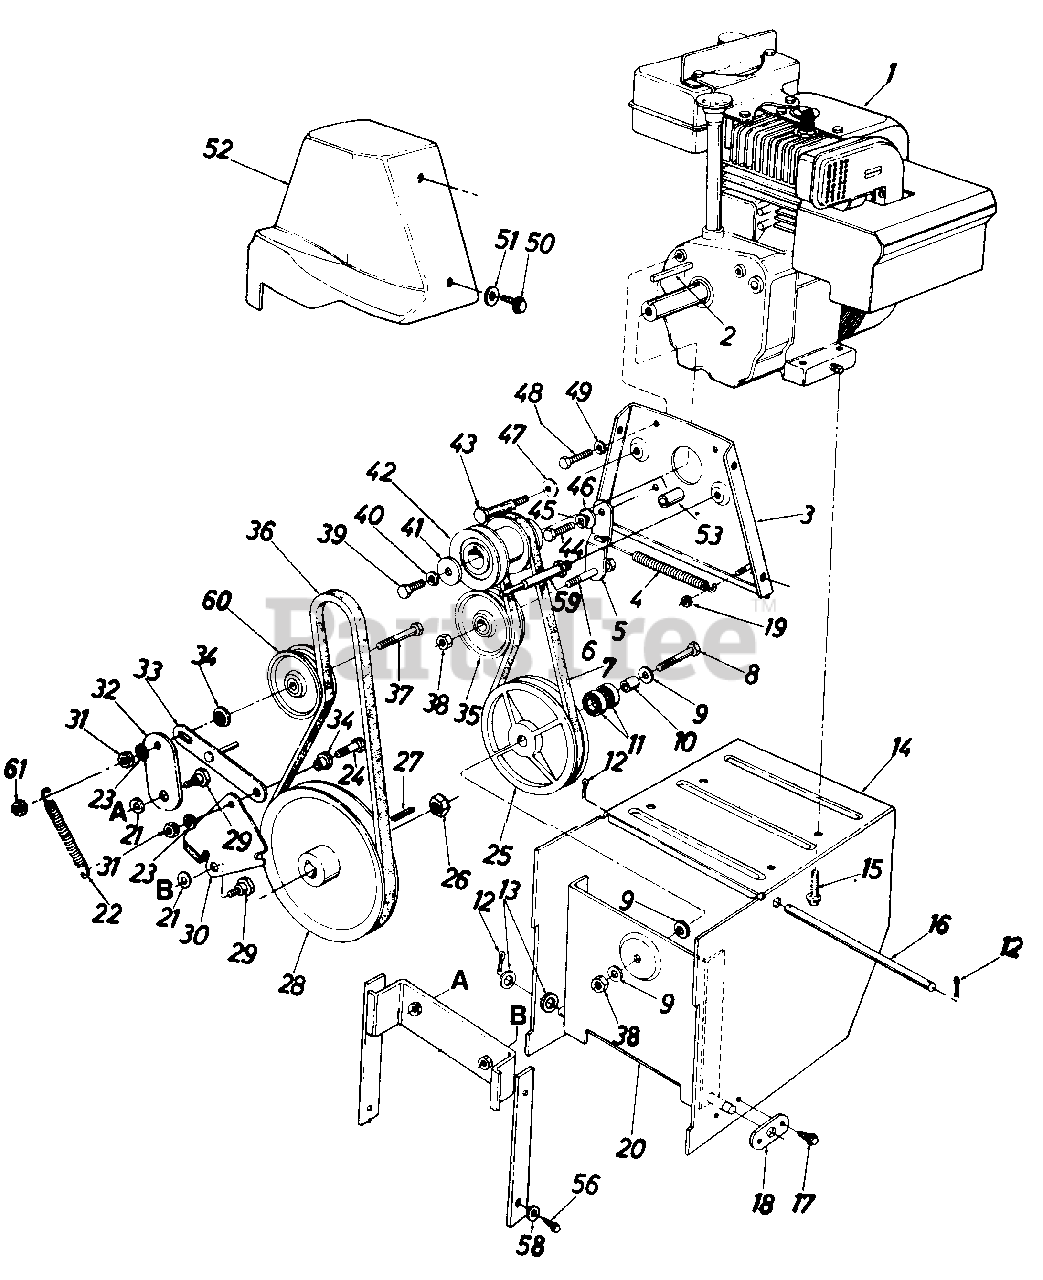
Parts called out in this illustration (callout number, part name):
1	Engine
2	Sq. Key 3/16" x 1.5" Lg.
3	Engine Plate Ass'y.
4	Extension Spring .50" O.D. x 3.97" Lg.
5	Drive Clutch Idler Brkt.
6	Hex Bolt 3/8-24 x 1.25" Lg.
7	"V Belt
8	Hex Bolt 3/8-24 x 1.50" Lg.
9	Bell-Wash. .40" I.D. x .88" O.D. x .06
10	Spacer .38" I.D. x .62" O.D. x.75" Lg.
11	Ball Brg. .62" I.D. x 1.38" O.D. x .44
12	Cotter Pin 3/32" Dia. x .75"
13	Fl-Wash. .53" I.D. x 1.00" O.D. x .125
14	Frame Ass'y.
15	Hex Wash. Hd. Self-Tap Scr. 3/8-16 x 1.25" Lg.
16	Shaft .50" Dia. x 9.50" Lg.
17	Hex Wash. Hd. Self-Tap Scr. 1/4-20 x .50" Lg.
18	Axle Bracket
19	Hex L-Nut 1/4-20 Thd.
20	Drive Pulley Support Brkt. Ass'y.
21	Bell-Wash. .40" I.D. x 1.13" O.D.
22	Extension Spring .5" O.D. x 4" Lg.
23	L-Wash. 3/8" I.D.
24	Hex Bolt 3/8-16 x 1.25" Lg.
25	6.00" O.D. Drive Pulley Ass'y.
26	Hex Jam Cent. L-Nut 5/8-18 Thd.
27	Sq. Key 3/16 x .75" Lg.
28	518" V-Pulley .628" I.D. x 7.50" O.D.
29	Shld. Bolt .625" Dia. x .170" Lg. (3/8-16)
30	Brake Bracket Ass'y.
31	Hex Ins. L-Nut 3/8-16 Thd.
32	Auger Clutch Idler Brkt.
33	Brake Linkage Ass'y.
34	Shld. Spacer .625l I.D.
35	Flat Idler 2.25" O.D.
36	"V"-Belt
37	Hex Bolt 3/8-16 x 2.00/ Lg.
38	Hex Ins. Jam L-Nut 3/8-24 Thd.
39	Hex Bolt 3/8-24 x 1.50 Lg.
40	L-Wash. 3/8 I.D.
41	Bell-Wash. .40 I.D. x 1.25" O.D.
42	Double Groove Engine Pulley
43	Shld. Scr. .498" x 3.0" Lg.
44	Hex Bolt 5/16-24 x 1.0 Lg.
45	L-Wash. 5/16" I.D.
46	Shld. Spacer .320 I.D.
47	Bell-Wash. .40" I.D. x .88"
48	Hex Bolt 5/16-24 x .62" Lg.
49	L-Wash. 5/16 I.D.
50	Hex Wash. Hd. Self-Tap Scr. 1/4-20 x .50" Lg.
51	Fl-Wash. .28" I.D. x .75" O.D. x .06
52	Belt Cover
53	Spacer
56	Hex Wash. Hd. Self-Tap Scr. 3/8-16 x .75' Lg.
58	L-Wash. 3/8 I.D. H.D.
59	Stud 3/8-16 x 3.37' Lg.
60	Flat Idler 3.12 O.D.
61	Hex Cent. L-Nut 3/8-16 Thd.
